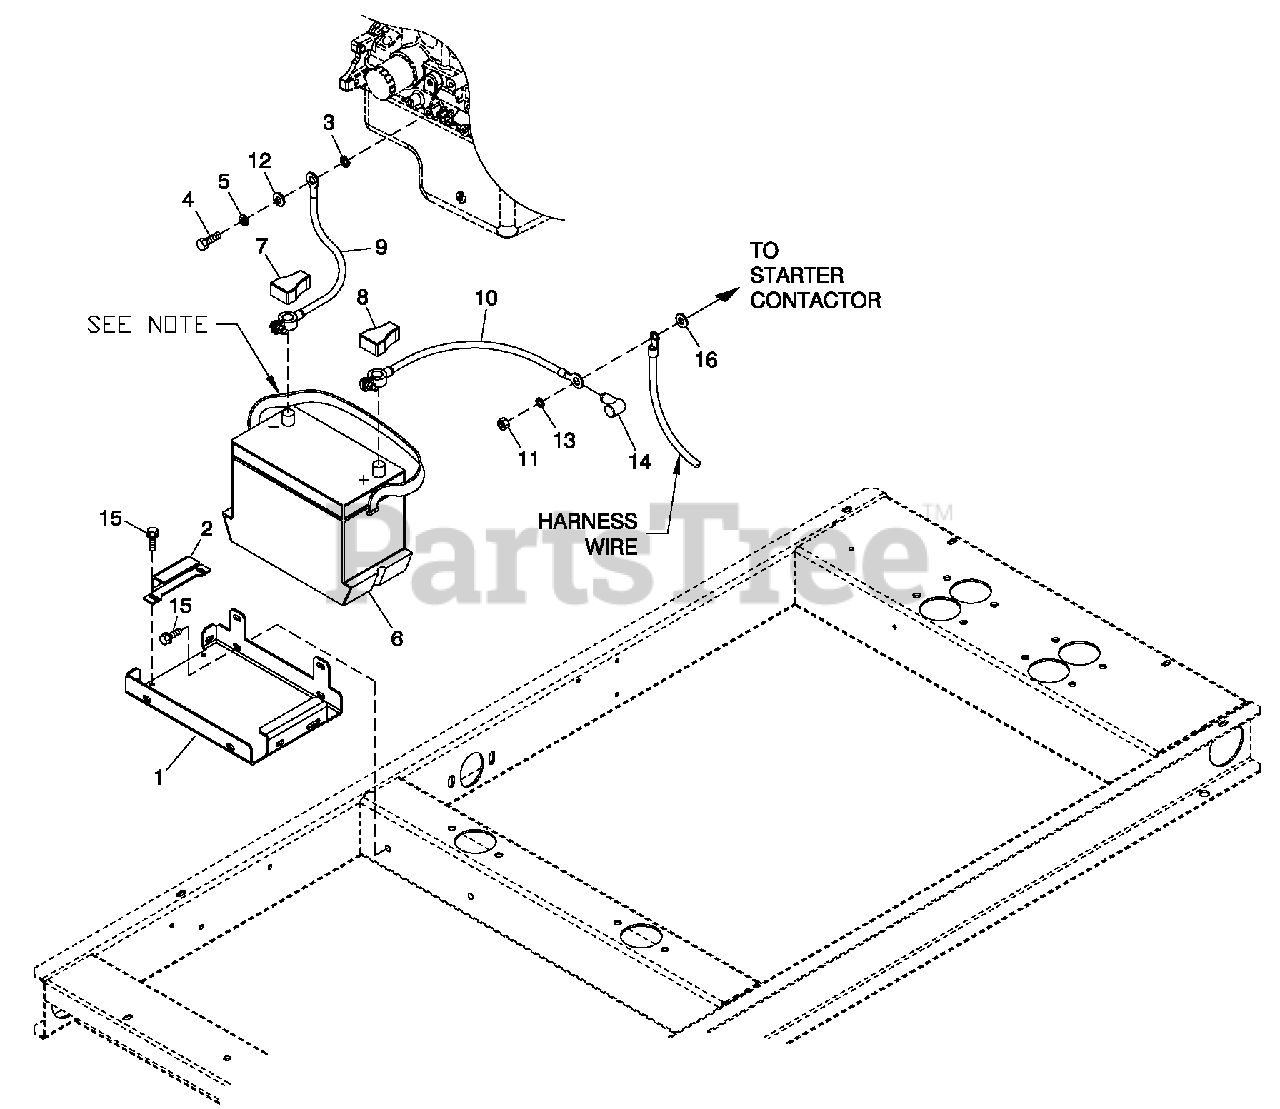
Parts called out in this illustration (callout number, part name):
1	BATTERY TRAY, C1&C2
2	STRAP BATTERY RETAINMENT
3	WASHER SHAKEPROOF EXT 7/16 STL
4	SCREW HHC M10-1.5 X 25 G10.9
5	WASHER LOCK M10
6	BATTERY 12VDC 75-AH 26
7	BATTERY POST COVER RED +
8	BATTERY POST COVER B LK -
9	CAB LE BATTERY B LACK #1 X 30.00
10	CAB LE BATTERY RED #1 X 21.00
11	NUTHEXM8-1.25 G8 YE L CHR
12	WASHER FLAT 3/8-M10 ZINC
13	WASHER SHAKEPROOF EXT 5/16 STL
14	BOOT CONTACTOR CAB LES
15	SCREW THF M6-1 X 16 N WA Z/JS
16	WASHER FLAT 5/16-M8 ZINC
